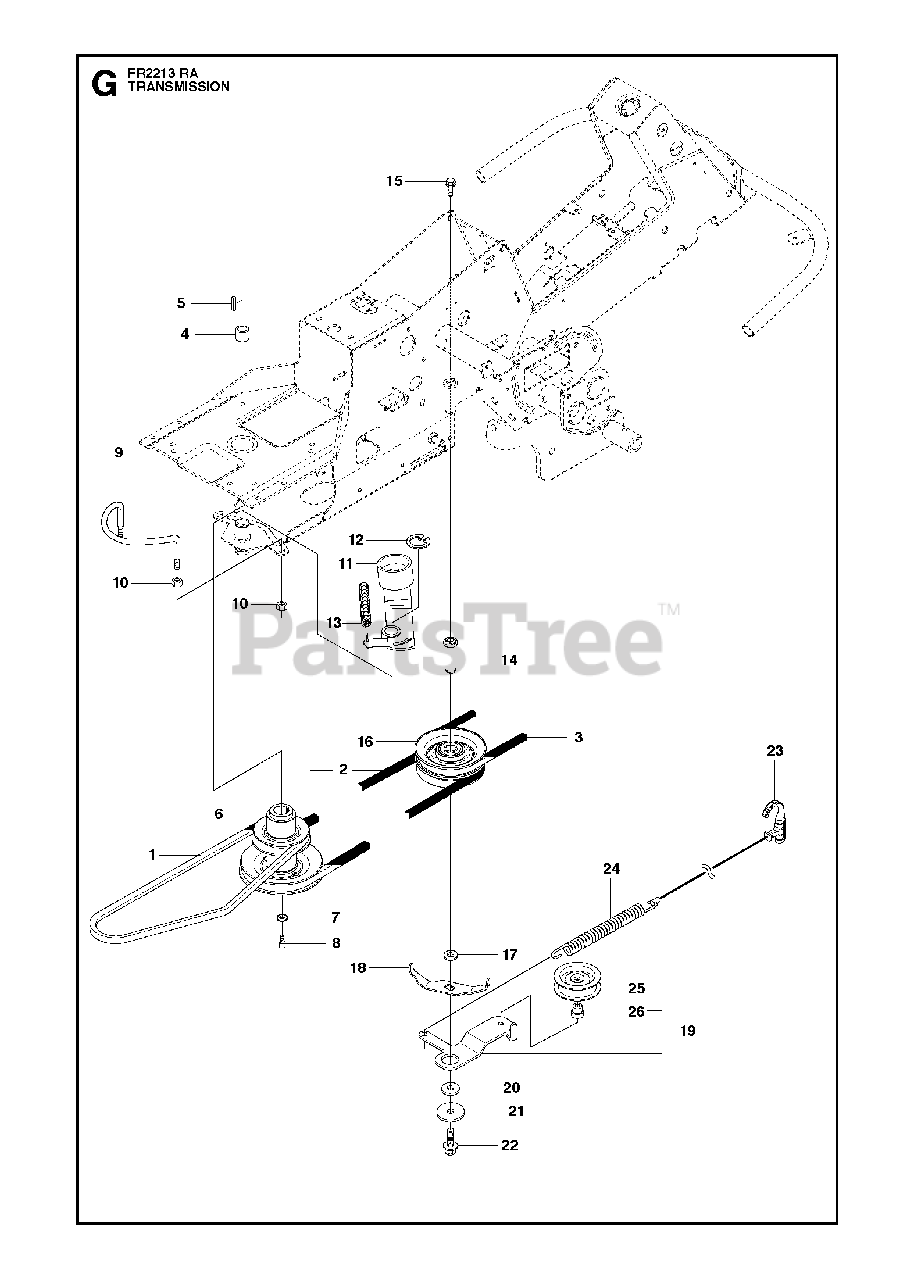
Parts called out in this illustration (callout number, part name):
1	BELT
2	BELT
9	BELT GUIDE
11	TENSIONER
12	RETAINING RING SGA 25
14	SHAFT
18	BELT GUIDE
22	BOLT
25	PULLEY
26	BUSHING
